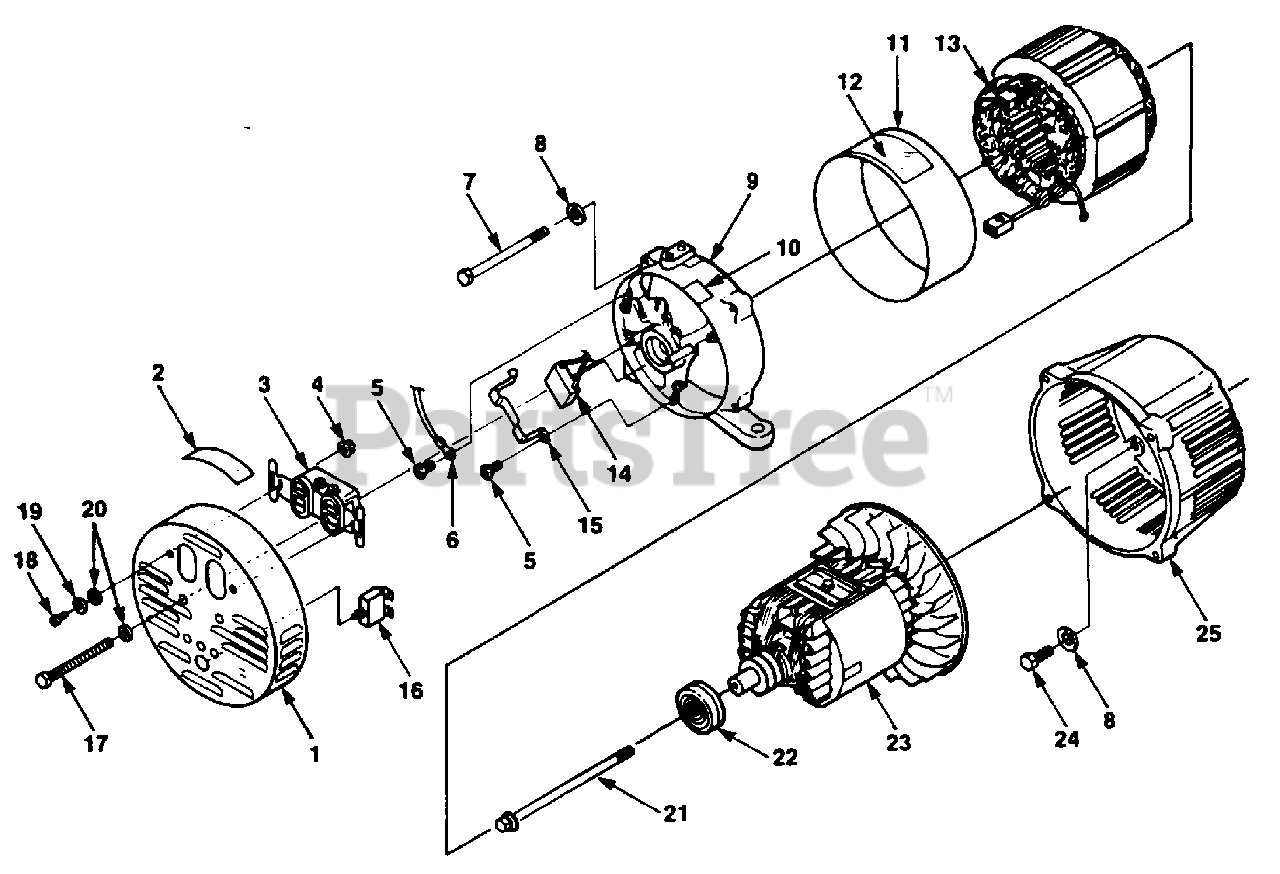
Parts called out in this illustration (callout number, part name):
1	END COVER
2	DECAL- Warning
3	RECEPTACLE (120V) (EH2500)
4	NUT (120V receptacle)
5	SCREW- (m5 x 12mm) (brush holder)
6	LEAD- Electrical (ground)
7	BOLT- Stator
8	WASHER- Lock ext./int.
9	END BELL
11	COVER- Stator
12	DECAL- Output
14	CAPACITOR
15	HOLDER- Capacitor
16	BREAKER- Circuit (20 amp)
17	BOLT- Cover (m5)
18	SCREW (120V receptacle)
19	WASHER- Lock
20	WASHER- Flat
21	BOLT- Rotor
22	BEARING- Ball
24	SCREW- Hex hd. (3/8-16 x 1")
